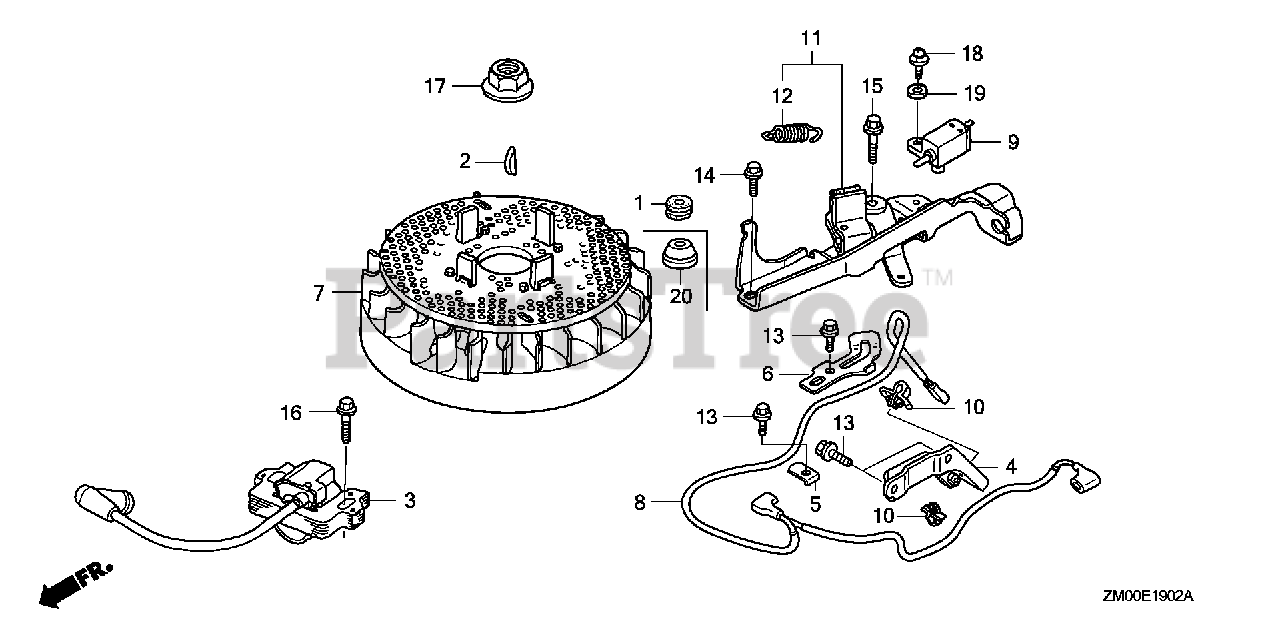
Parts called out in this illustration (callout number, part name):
2	KEY, SPECIAL WOODRUFF (25X18)
3	COIL ASSY., IGNITION (USE FOR F/W OF TEC) (TEC) Use up to Engine SN 3747197.
3	COIL ASSY., IGN
3	COIL ASSY., IGNITION (PHELON)
4	CLAMP, STOP SWITCH WIRE
5	CLAMP, STOP SWITCH WIRE
6	CLAMP, WIRE
7	FLYWHEEL ASSY. (TEC) (USE FOR IGN. COIL OF TEC)
8	WIRE, STOP SWITCH
9	SWITCH ASSY., ENGINE STOP (Honda Code 5580683). (N.C)
10	HOLDER, WIRE (FASTEX)
10	CLIP, CABLE (A)
11	BRAKE SUB-ASSY.
12	SPRING, BRAKE LEVER
13	BOLT, FLANGE (6X12) (CT200)
14	BOLT, FLANGE (6X14)
15	BOLT, FLANGE (6X23)
16	BOLT, FLANGE (6X23)
17	NUT, SPECIAL (14MM)
18	SCREW-WASHER (4X12)
19	WASHER, PLAIN (4MM)
20	GROMMET, BRAKE PLATE
